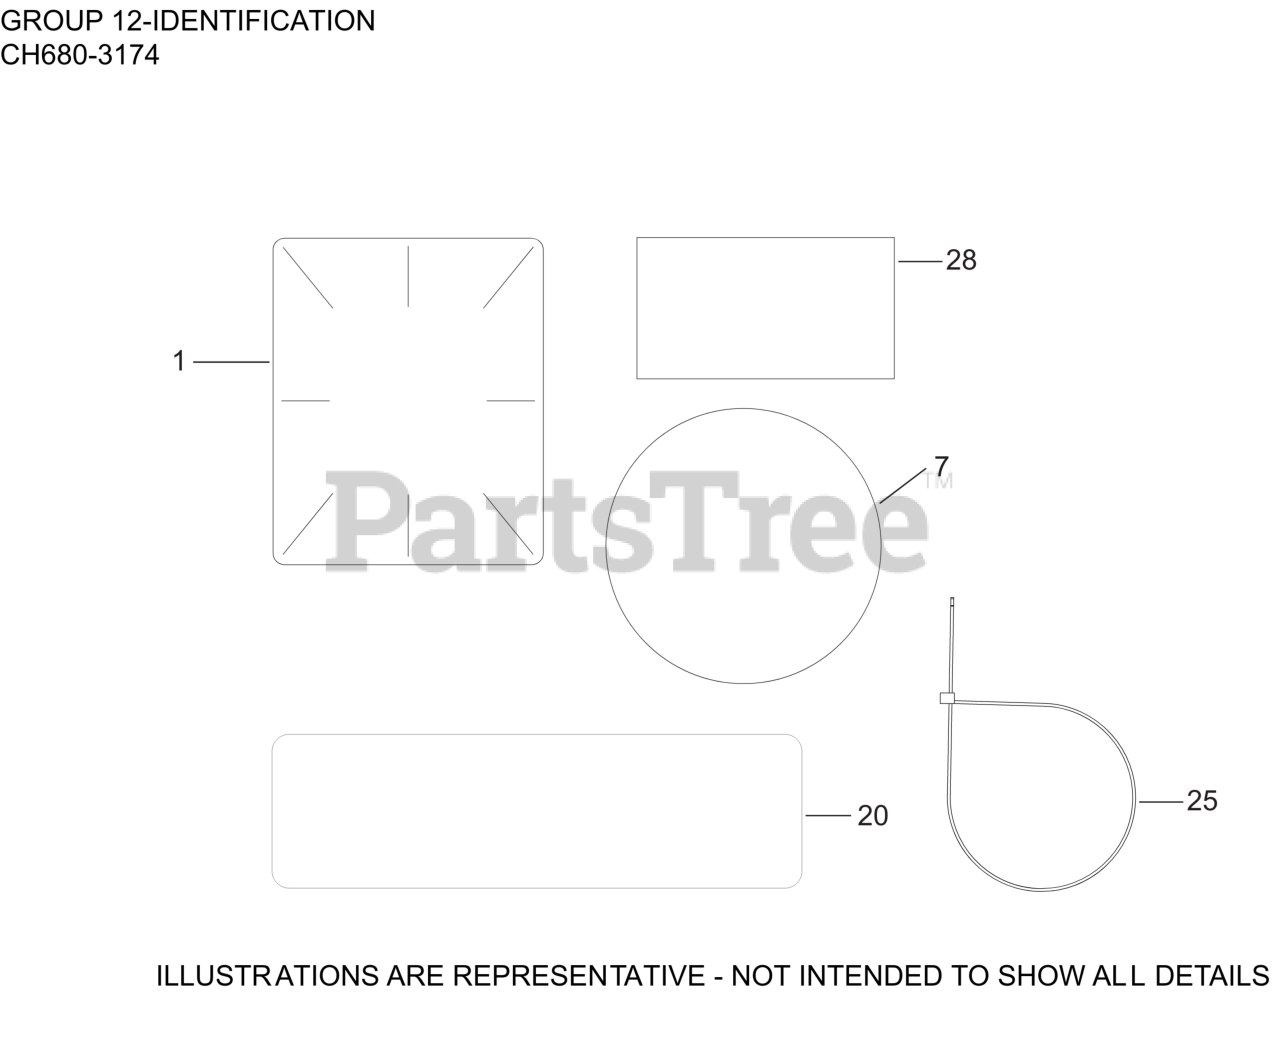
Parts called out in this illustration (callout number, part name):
1	LABEL, CLEAR LAMINATION
7	LABEL, GRASS SCREEN
20	DECAL LPAC, 22.5 HP/674cc/CH680
28	DECAL, USA
